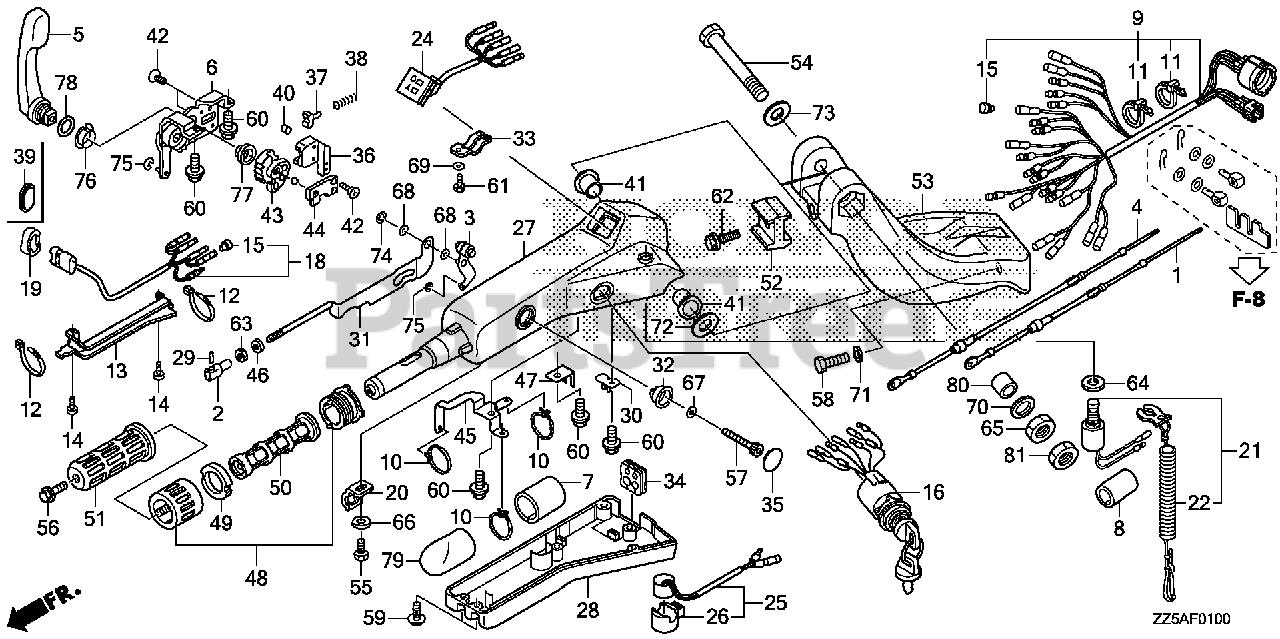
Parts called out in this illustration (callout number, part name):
1	CABLE, THROTTLE
2	PIVOT, THROTTLE CABLE
3	ARM, THROTTLE
4	CABLE, SHIFT
5	LEVER, SHIFT
6	FRAME ASSY., SHIFT
7	TUBE (38.1X40)
9	CABLE ASSY., LONG HANDLE (A)
10	BAND (CONVEX CV-150)
11	BAND (CONVEX CV-200)
12	BAND (CONVEX)
13	COVER, WIRE
15	PLUG, CONNECTOR (INNER)
16	SWITCH ASSY., COMBINATION
20	HOLDER, SWITCH
21	SWITCH ASSY., EMERGENCY STOP
22	WIRE, EMERGENCY
24	LAMP ASSY., INDICATOR
25	BUZZER ASSY., WARNING
26	SUSPENSION, WARNING BUZZER
27	HOUSING *NHB14M* (AQUA MARINE SILVER METALLIC)
28	COVER, HANDLEBAR (LOWER)
29	PIN, THROTTLE CABLE
30	BRACKET, CABLE
31	PLATE ASSY., LOCK
33	PLATE, GUIDE
36	GUIDE, SPRING
38	SPRING, COIL
39	GROMMET, POWER TILT SWITCH
41	BUSH, HANDLEBAR
42	SCREW (M5X14)
43	GEAR, SHIFT
44	PLATE, BALL GUIDE
46	ROD, GROMMET
47	CLAMP, BRACKET
48	GRIP ASSY., THROTTLE FRICTION
49	PAD, THROTTLE FRICTION
50	PIPE, GRIP
51	RUBBER, GRIP
52	BLOCK, HEIGHT ADJUSTER
53	BRACKET, STEERING *NHB14M* (AQUA MARINE SILVER METALLIC)
54	BOLT, HEX. (12X80)
55	BOLT (M5X8)
56	BOLT, FLANGE (6X12)
57	BOLT (M8X50)
58	BOLT, HEX. (10X32)
59	BOLT (M5X12)
60	BOLT (M6X12)
61	BOLT (M5X12)
62	BOLT, FLANGE (8X28)
63	NUT, HEX. (5MM)
64	NUT, HEX. (16MM)
65	NUT, HEX. (12MM)
66	WASHER (5MM)
67	WASHER (8MM)
68	WASHER (10MM)
69	WASHER (5MM)
70	WASHER, WAVE (14MM)
71	WASHER (10MM)
72	WASHER, PLAIN (12MM)
73	WASHER, PLAIN (12MM)
78	O-RING (20.6X1.9)
79	TUBE, CORD (40MM)
80	COLLAR, DISTANCE (12.2X23X16)
81	NUT, HEX. (12MM)
